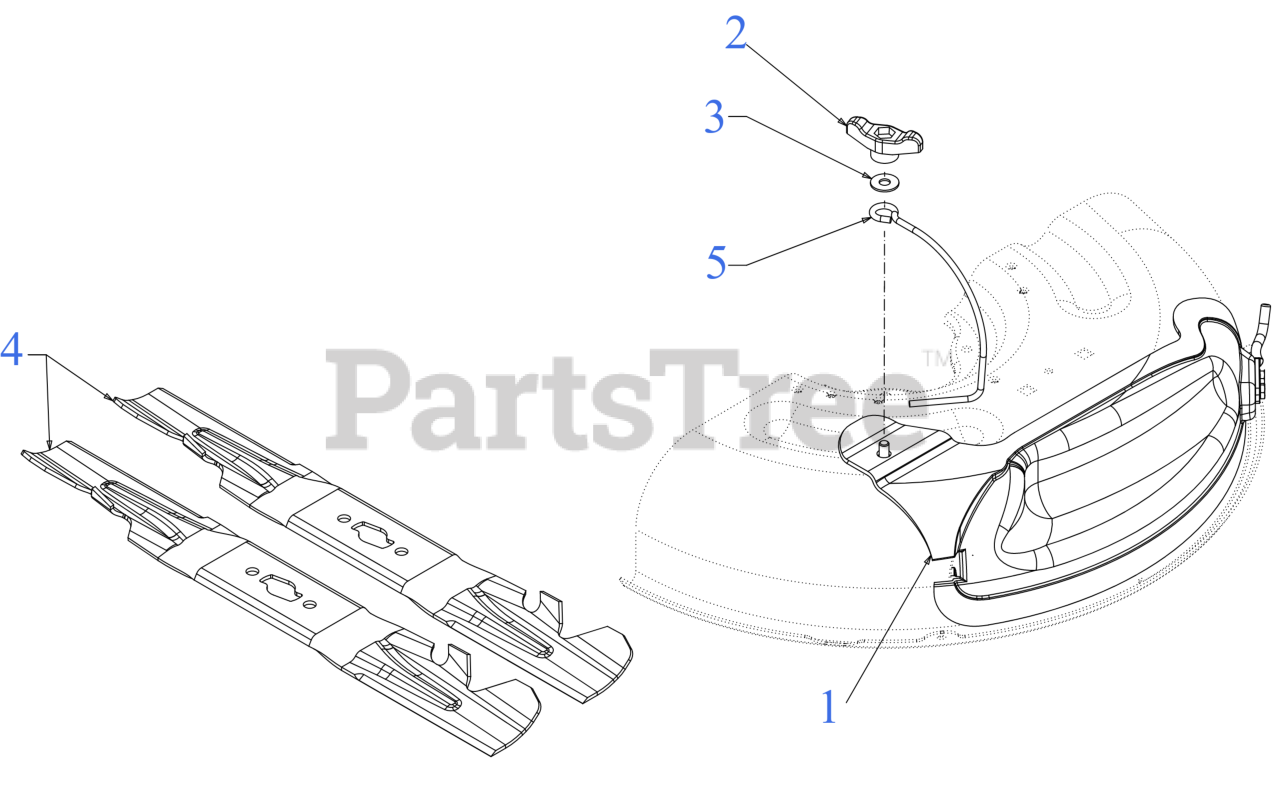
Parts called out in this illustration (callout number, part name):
1	MULCH PLUG ASSEMBLY
2	WING KNOB 5/16-18
3	FLAT WASHER
4	21.23" XTREME BLADE (2IN1) (S SHAPE CENTER HOLE)
5	MULCH PLUG SUPPORT ROD
